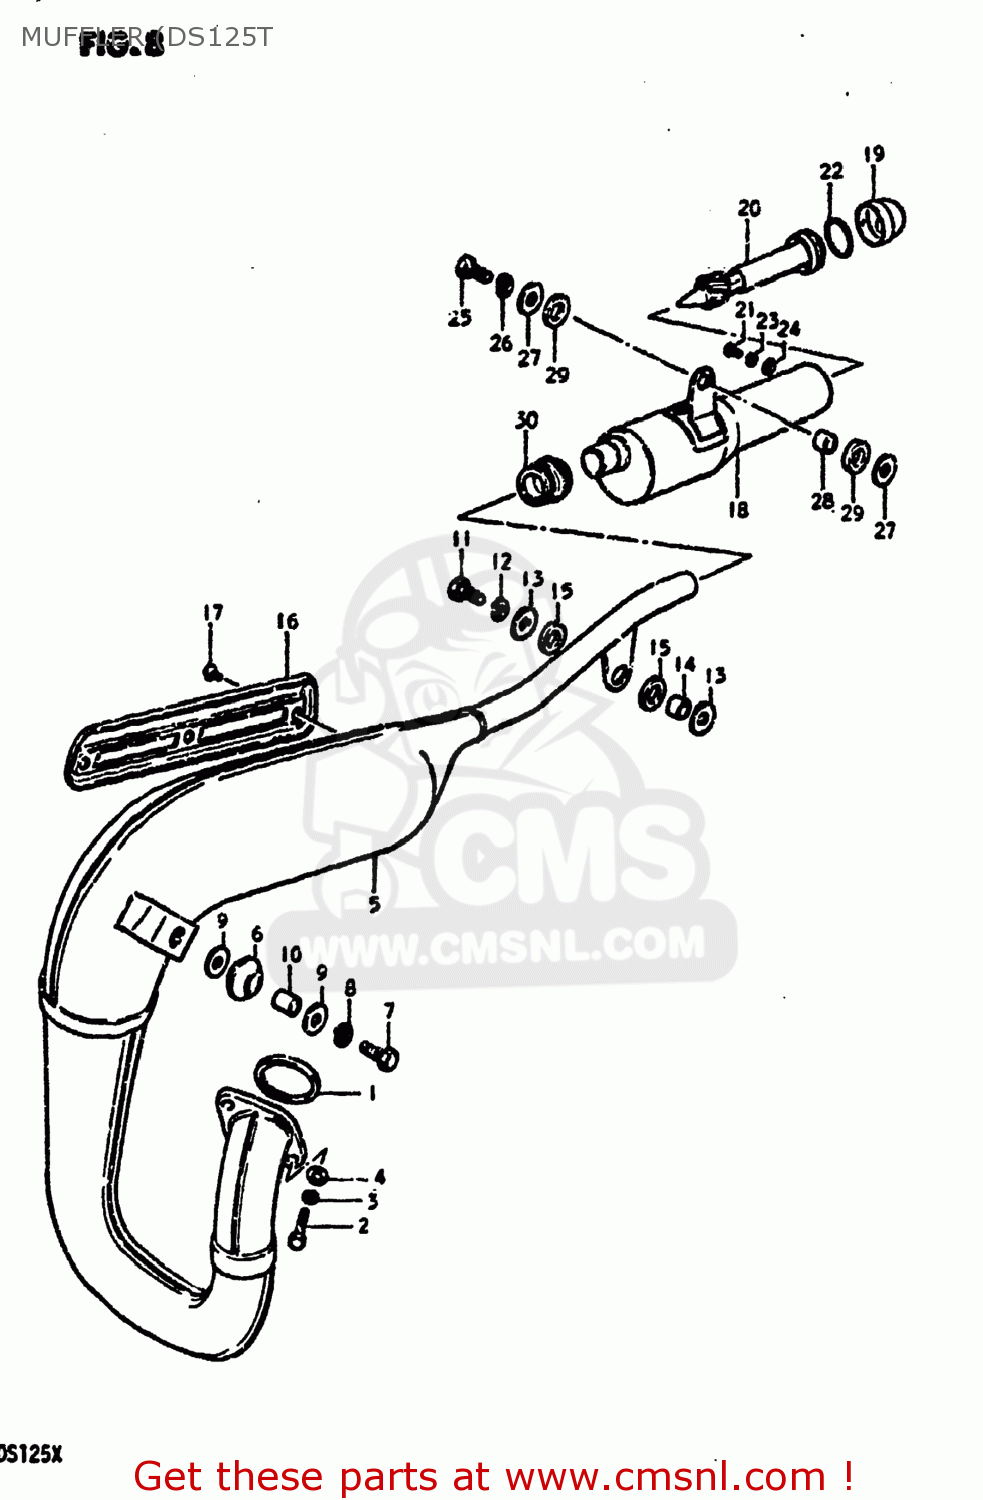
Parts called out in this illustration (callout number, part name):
1	GASKET,EXHAUST PIPE (NAS)
2	SCREW (6X25)
3	LOCK WASHER
4	WASHER
5	BODY,MUFFLER
6	DAMPER,MUFFLER,FR
7	BOLT
8	LOCK WASHER
9	WASHER (8.7X22X2)
10	SPACER (8X12X15)
11	BOLT
12	LOCK WASHER
13	WASHER
14	SPACER (8.6X13.8X9.8)
15	CUSHION
16	COVER,MUFFLER
17	SCREW
18	MUFFLER ASSEMBLY
19	COVER,SECOND MUFFLER TAIL
20	TUBE,MUFFLER CLEAN OUT
21	SCREW(6X8)
22	O-RING (D:3.5 ID:54.4)
23	LOCK WASHER
24	WASHER
25	BOLT
26	LOCK WASHER
27	WASHER
28	SPACER (8.6X13.8X9)
29	CUSHION
30	CONNECTOR,MUFFLER
